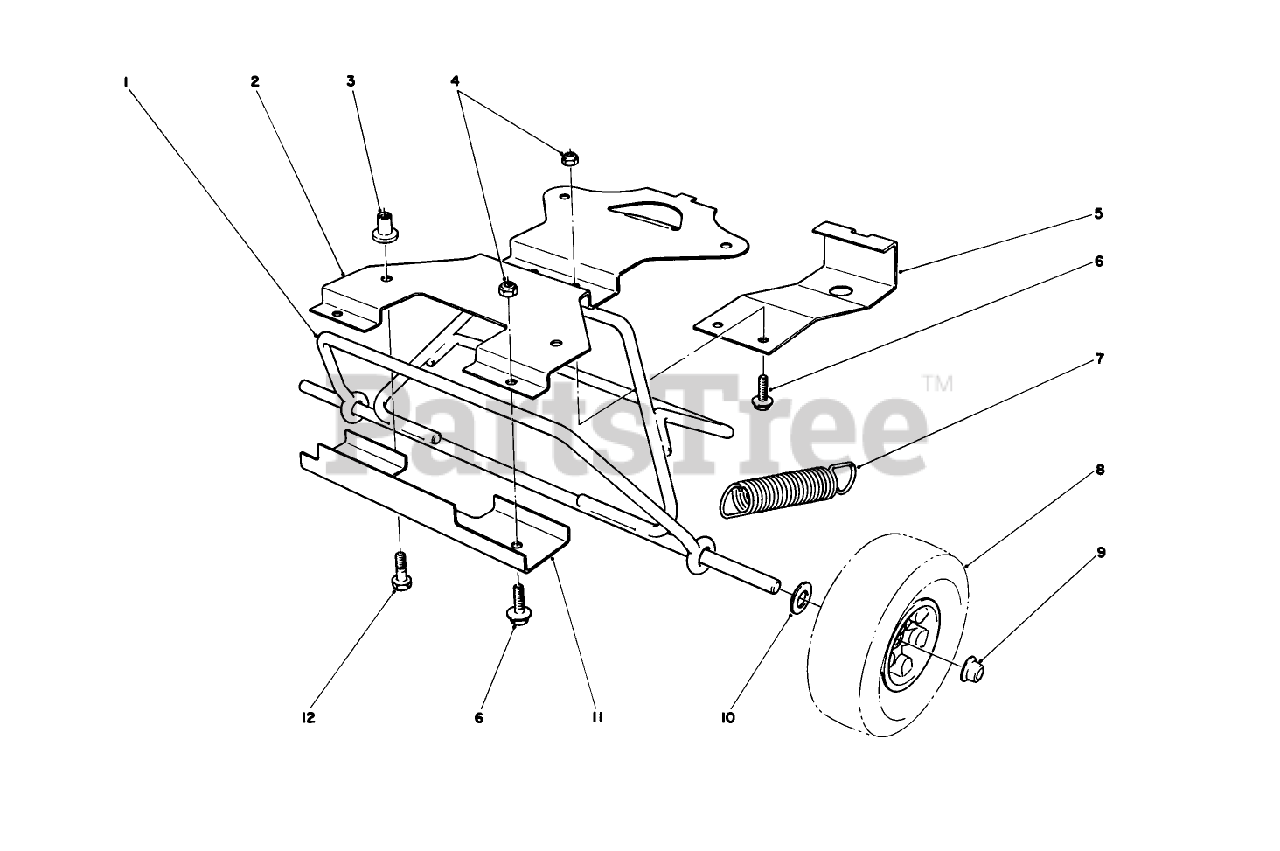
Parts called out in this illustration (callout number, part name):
1	AXLE WA
2	WHEEL PLATE
3	WELLNUT
4	NUT-LOCK, NI
5	COVER
6	SCREW-SHWH
7	EXTENSION SPRING
8	S-120 WHEEL
9	PUSHNUT-CAP, WASHER
10	WASHER-PLAIN
11	AXLE RETAINER
12	MTG SCREW
